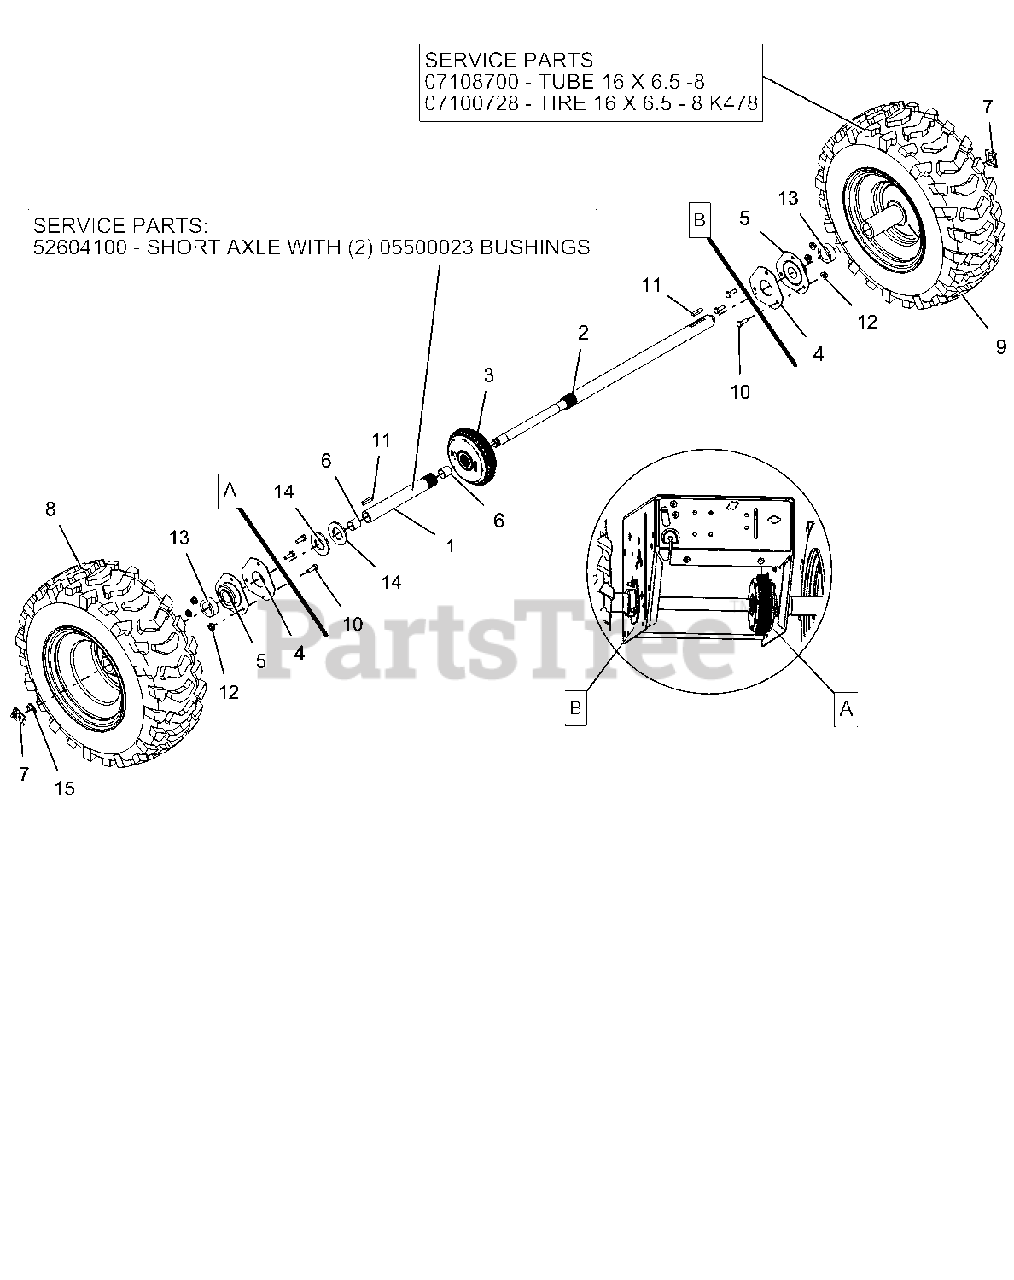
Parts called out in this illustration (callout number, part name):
1	AXLE, SHORT-PRO AUTO DIFF
2	AXLE, LONG-PRO AUTO DIFF
3	DIFFERENTIAL, AUTOMATIC
4	PLATE, BEARING SPACER
5	BRG-FLG 1.003/1.000 3 BOLT
6	BSHG-SLV .706X.764X.75 BRZ
7	CLIP, SNAP .625 DIA
8	TIRE/WHEEL, RH 16X6.50-8 DIFF
9	TIRE/WHEEL, LH 16X6.50-8 DIFF
10	@BLT-HEX .25-20X.75 GR5 YWZC
11	KEY-RECT .25X.188X1.00
12	@NUT-LK-CTR-FLG .25-20 YWZC
13	SPACER, PRO AXLE BEARING
14	WSHR-FL-STL- 1.062X2.0X.134 YZ
15	RG-RTNG-EXT .625X.042
16	TUBE
17	TIRE, 16X6.50-8 K478
18	AXLE, SHORT-AUTO W/BUSHINGS
